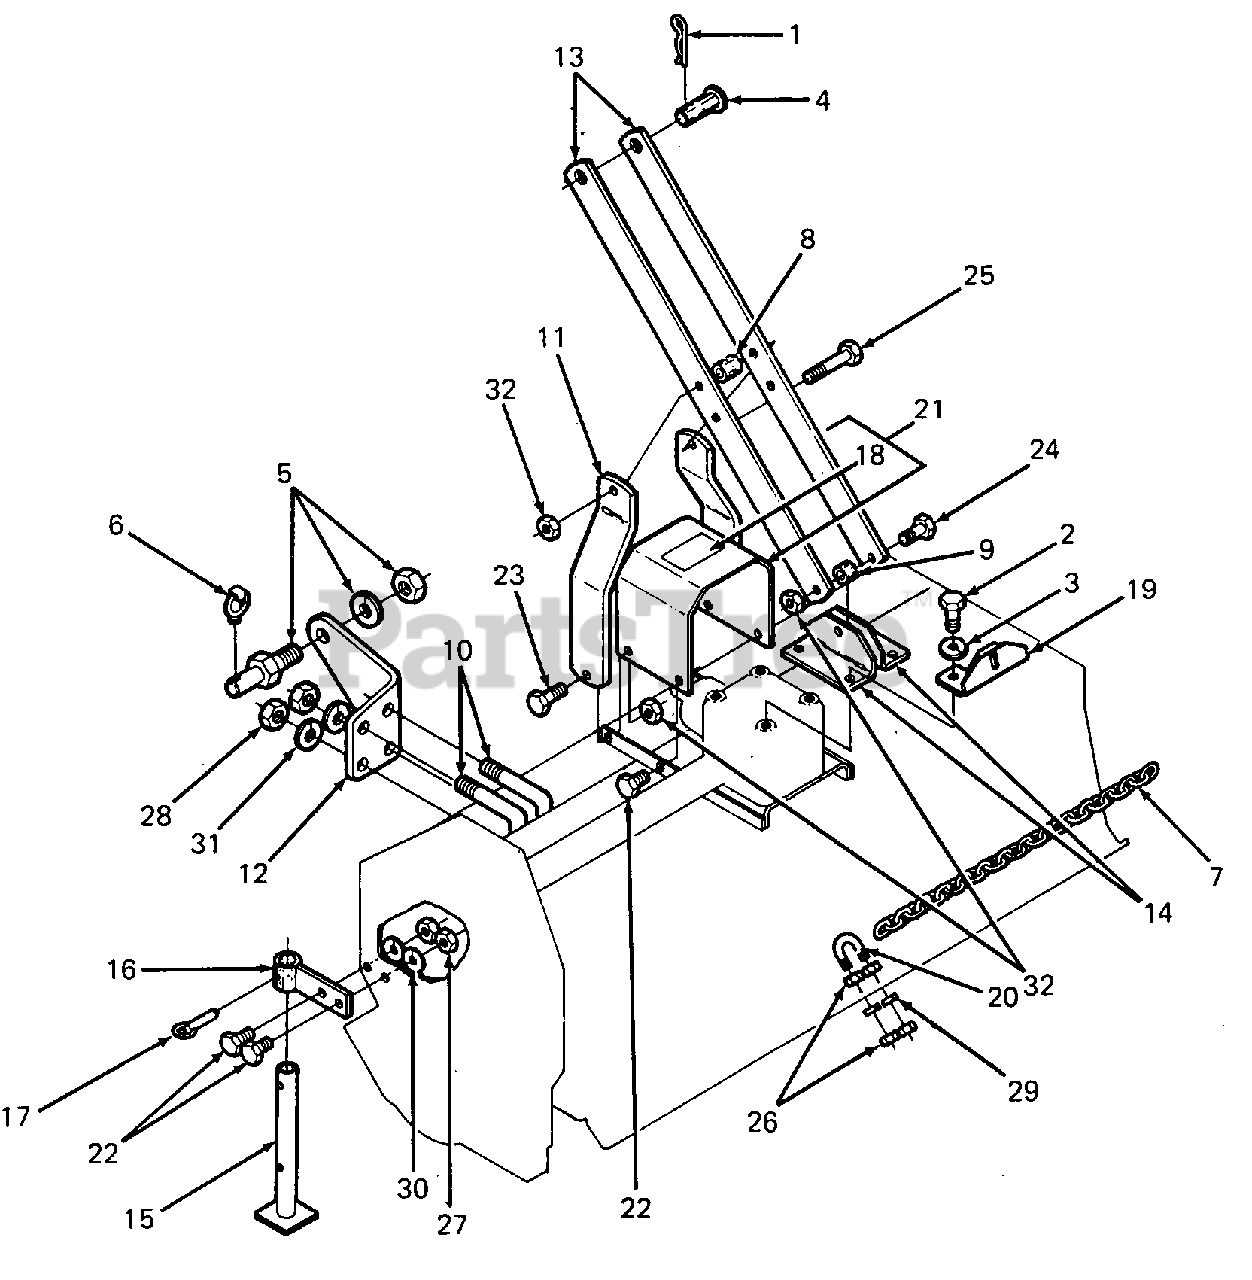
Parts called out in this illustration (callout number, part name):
1	Pin, Hair
2	Screw, Hex Cap, M10 X 22 mm Lg GR 8.8
3	Washer, Lock, M10
4	Pin, Clevis
5	Pin, Lift Arm
6	Pin, Lynch
8	Bushing, Top Link, 1-1/16 Lg
9	Bushing, Mast, 9/16 Lg
10	U-Bolt, 1/2-13 Trd
11	Bar, Mast
12	Hitch Lug LH
13	Toplink Mast
14	Mast Support
15	Parking Stand
16	Securing Stand
18	Decal, Caution
19	Chain Retainer
20	U-Bolt, 1/4-20
21	PTO Shield w/Decal
22	Screw, Hex Cap, 3/8-16 X 1.0 Lg GR 5
23	Screw, Hex Cap, 3/8-16 X 1-1/2 Lg GR 5
24	Screw, Hex Cap, 3/8-16 X 2-1/4 Lg GR 5
25	Screw, Hex Cap, 3/8-16 X 3-1/2 Lg GR 5
26	Nut, Hex, 1/4-20
27	Nut, Hex, 3/8-16
28	Nut, Hex, 1/2-13
29	Washer, Lock, 1/4
30	Washer, Lock, 3/8
31	Washer, Lock, 1/2
32	Nut, Hex Lock, 3/8-16
